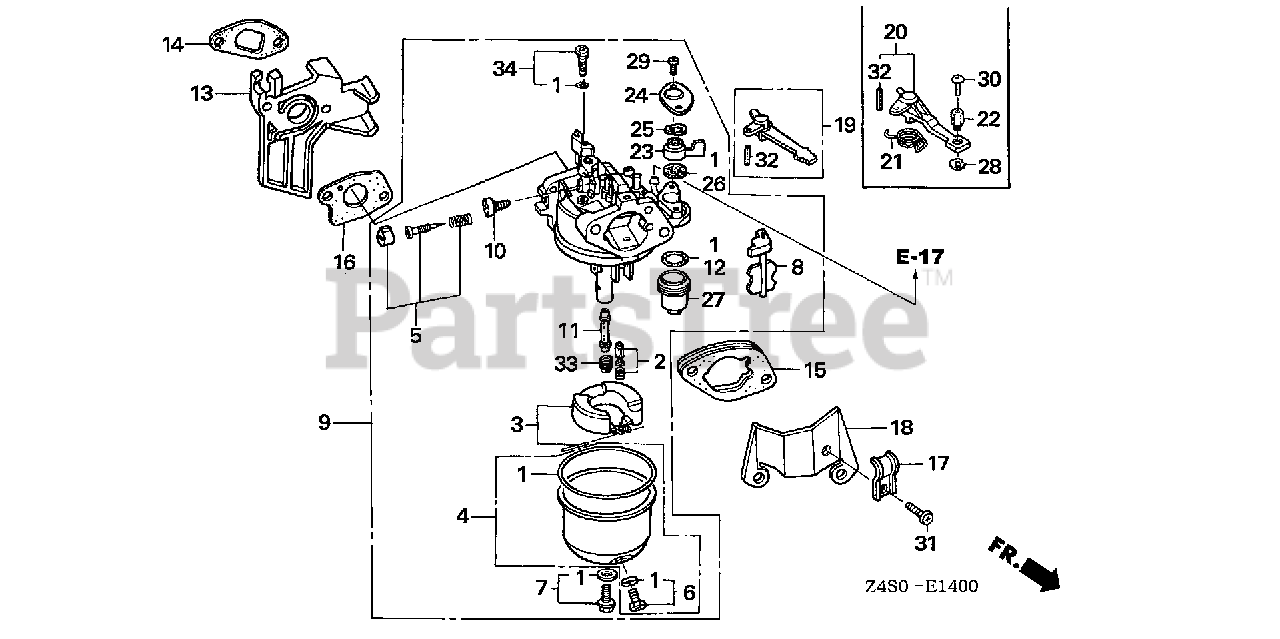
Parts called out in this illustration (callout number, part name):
1	GASKET SET
2	VALVE SET, FLOAT (CARBURETOR NO.) (SEAT NOT INCLUDED)
3	FLOAT SET
4	CHAMBER SET, FLOAT (CARBURETOR NO.)
5	SCREW SET (Honda Code 4219879). (CARBURETOR NO.)
6	SCREW SET, DRAIN (Honda Code 1672187). (CARBURETOR NO.)
7	SCREW SET B
7	SCREW SET
8	CHOKE SET
9	CARBURETOR ASSY. (BE64B B/C)
10	SCREW, THROTTLE STOP
11	NOZZLE, MAIN
12	GASKET, FUEL STRAINER CUP
13	INSULATOR, CARBURETOR
14	GASKET, INSULATOR
15	SPACER, CARBURETOR
16	GASKET, CARBURETOR
19	LEVER, CHOKE (STD)
23	LEVER, VALVE
24	PLATE, LEVER SETTING (CARBURETOR NO.)
25	SPRING, PETCOCK LEVER (CARBURETOR NO.)
26	GASKET, VALVE
27	CUP, FUEL STRAINER
29	SCREW, PAN (3X6)
32	PIN, SPRING (2X12)
33	JET, MAIN (#72) (CARBURETOR NO.)
33	JET, MAIN (#68)
33	JET, MAIN (#70)
34	JET SET, PILOT (#45)
